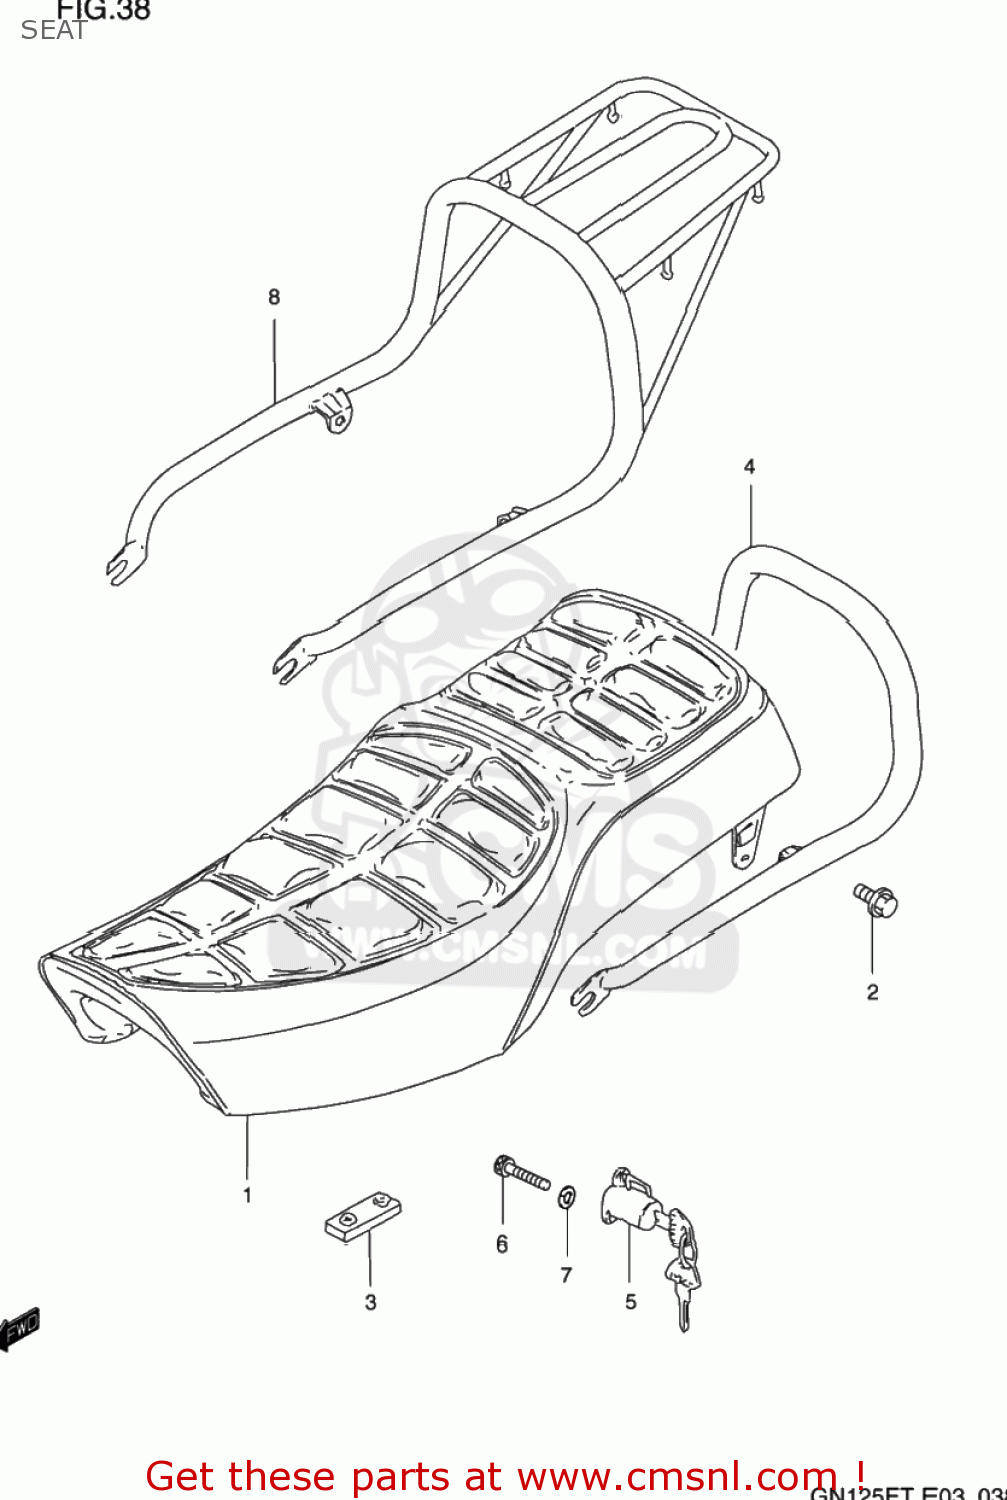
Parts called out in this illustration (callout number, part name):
1	SEAT ASSY
2	BOLT
3	CUSHION
4	HANDLE,PILLION RIDER
5	LOCK SET,HELMET
6	SCREW
7	WASHER,LOCK
8	CARRIER
